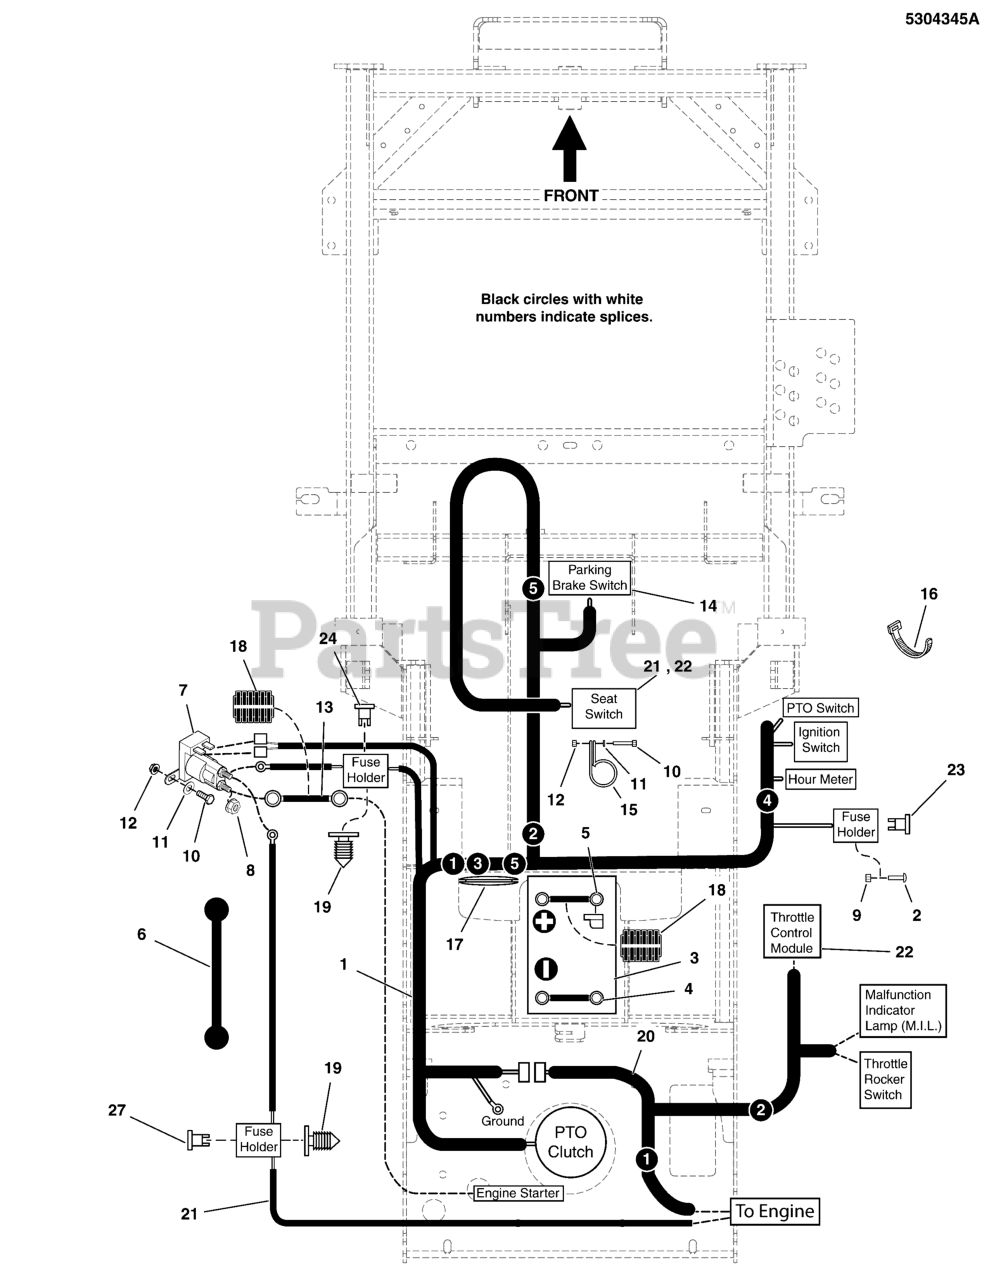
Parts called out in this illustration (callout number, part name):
1	WIRE HARNESS, MAIN, SM, ZTR
3	BATTERY, WET ( BCIU1, 350 CCA)
4	BATTERY CABLE, NEG, 14, 5/16-13/32
5	BATTERY CABLE, POS, 22, 1/4-5/16
6	STRAP, BATTERY, 14 LONG, Rubber
7	SOLENOID, STD-BRACKET, 2-SPADE
8	NUT,1/4-20,KEPS,CONICAL WSHR,ZC/CL
9	NUT, Hex, 5/16-24
10	BOLT, 1/4"-20 X 3/4" GD5 YZ
11	WASHER, 1/4 SAE
12	NUT, 1/4-20 Hex Nylock Flange
13	BATTERY CABLE, POS, 22, 1/4-5/16
14	SWITCH, DP NO/NC SNAP-IN
15	CLAMP, VINYL INSULATED, 1.00
16	TIE, SELF-LOCKING, 12"
17	GROMMET, 1-1/2" ID FOR 1/4" METAL
18	WIRE LOOM, 3/8 ID X 18 IN
19	FIR TREE MOUNT, PACKARD
20	WIRE HARNESS, JUMPER FX730V, EFI, IS700
21	HARNESS, KAWI, FS, EFI CHARGE JUMPER
22	MODULE, THROTTLE CONTROL, KAV DFI
23	SWITCH, NC, W/ BOLT-IN BASE
24	SWITCH, NC, W/ TWIST-IN BASE
25	FUSE, ATO-15 (15 AMP)(SV)
26	FUSE, ATO-20 (20 AMP)(SV)
27	FUSE, ATO-40 (40 AMP)
